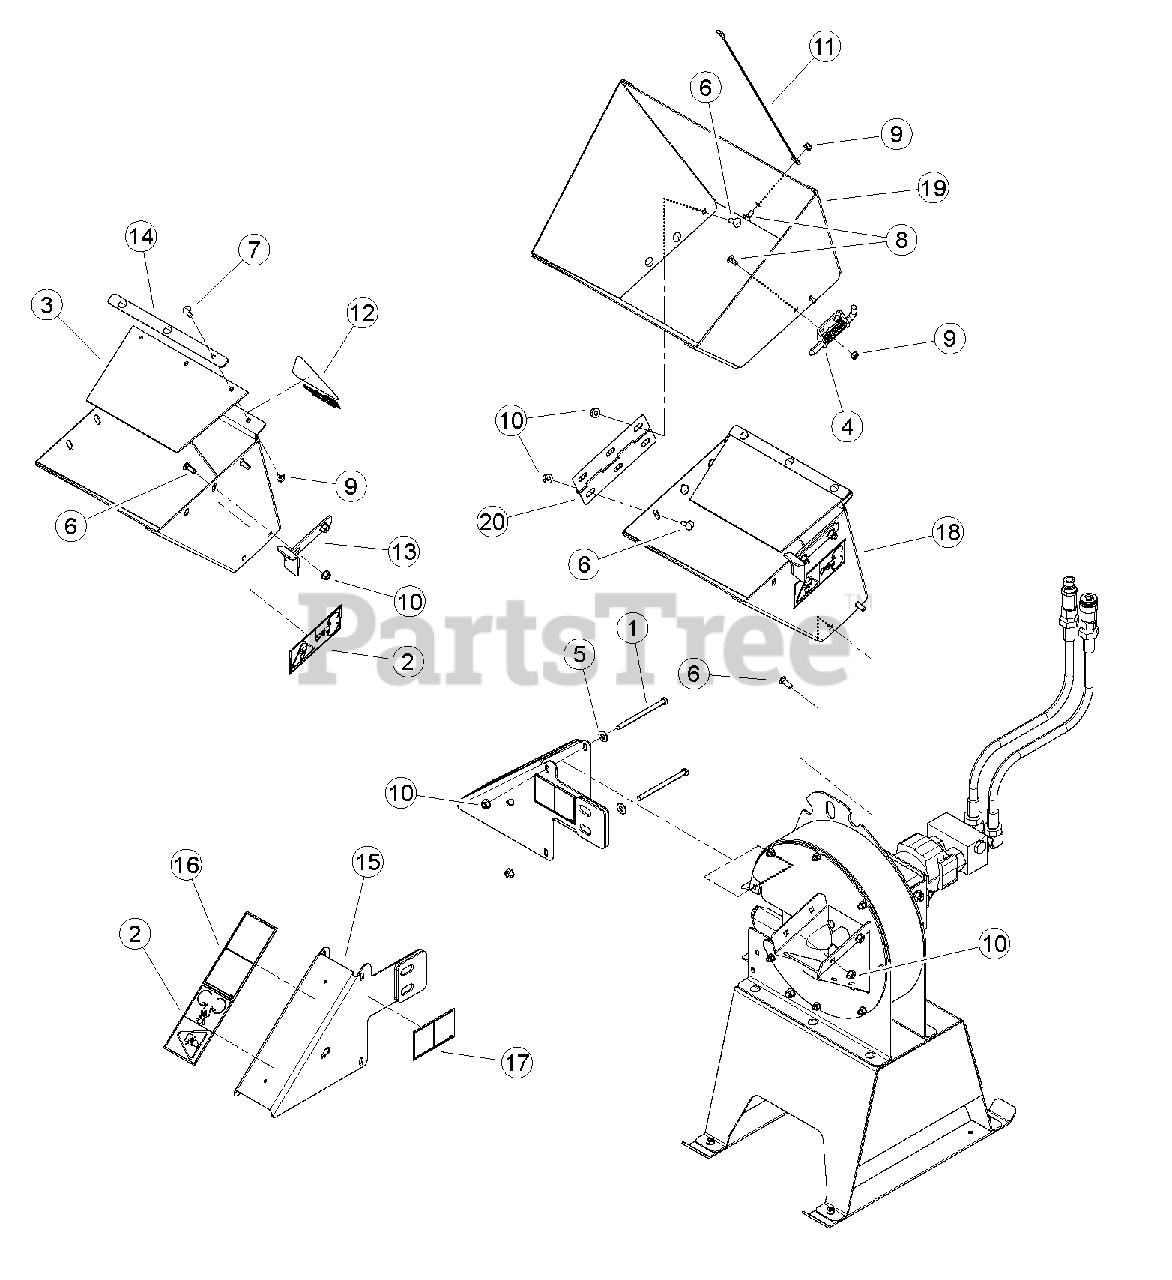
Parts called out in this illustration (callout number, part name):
1	BOLT, 3/8 X 5-1/2 HEX GR5 ZP
2	DECAL, BLADE DANGER ISO
3	FLAP, CHIPPER CHUTE
4	LATCH, RH HINGE
5	WASHER, 3/8" FLAT ZP
6	BOLT, 3/8 X 1" CRG GR5 NC ZP
7	BOLT, 5/16 X 1" GR5 CRG ZP
8	BOLT, 5/16 X 3/4" GR5 NC ZP CRG
9	NUT, 5/16-18 NYLOCK-FLANGE
10	NUT, 3/8-16 NYLOCK FLANGE
11	LANYARD, STEEL W/ PVC 1/8 X 20"
12	DECAL, CHIP IT
13	PLATE, EXT. LOCK
14	STRIP, FLAP RETAINER
15	ASSEMBLY, DISCHARGE CAP
16	DECAL, KNIFE ACCESS ISO
17	DECAL, DISCHARGE ISO
18	WELDMENT, HOPPER
19	WELDMENT, HOPPER EXT. 4-1/2 PTO
20	HINGE, CHUTE EXT
